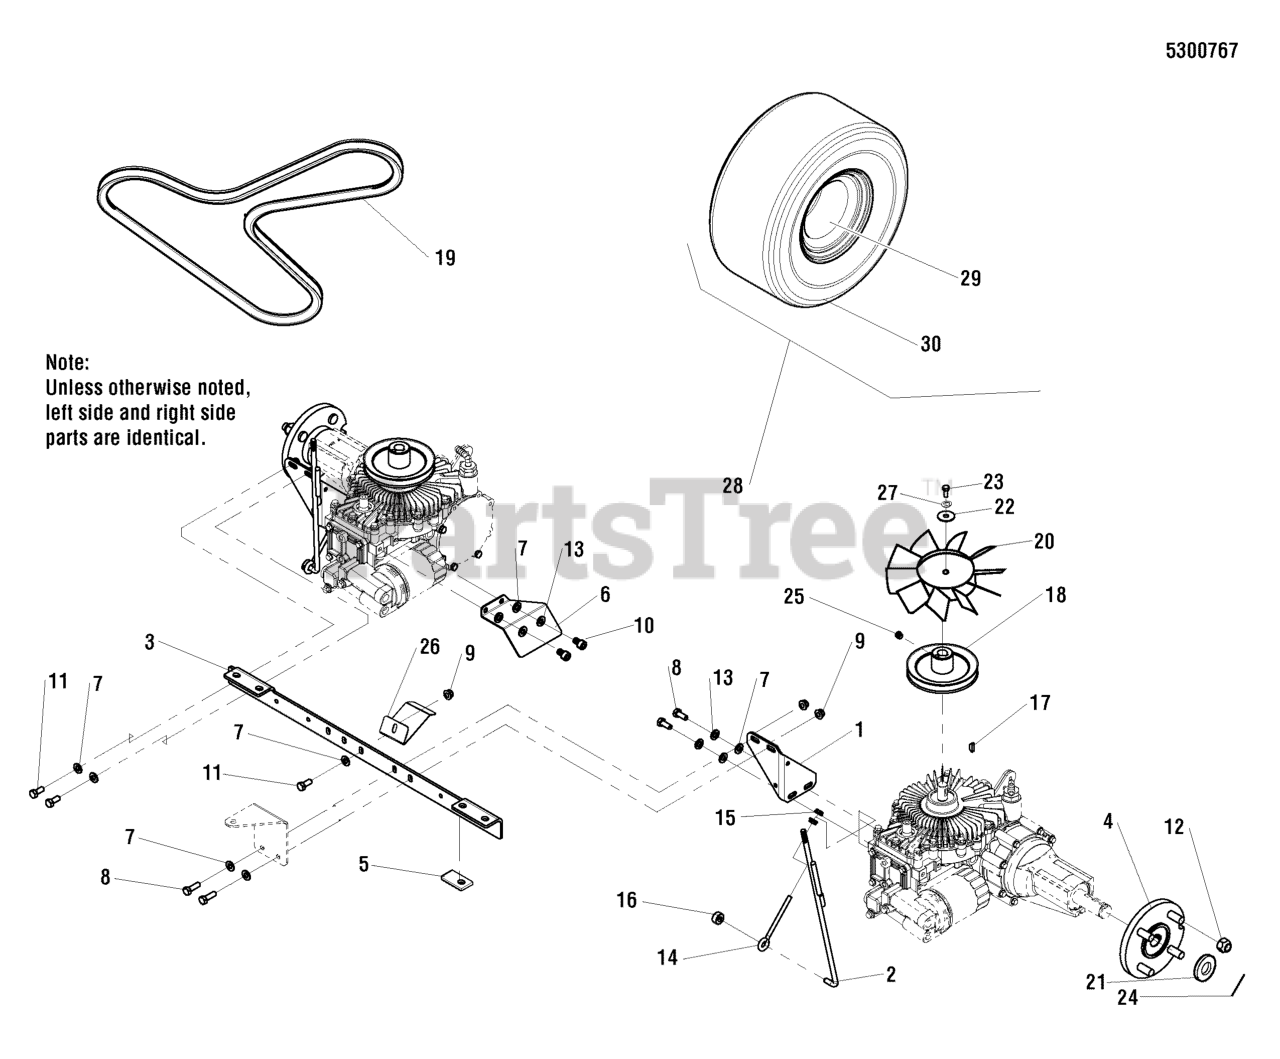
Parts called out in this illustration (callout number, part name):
1	MOUNT, TRANMISSION
3	BRACE, TRANSMISSION
4	HUB, 4-Bolt Tapered
6	GUARD, OIL FILTER
7	WASHER, 5/16" SAE
8	BOLT, 5/16-18 X 1" GRD5 YZ
9	NUT, 5/16-18 HEX NYLOCK FLANGE NUT
10	BOLT, 5/16-18 X 3/4 12PT FLANGE - PATCH
11	BOLT, 5/16-18 X 3/4 GD5
12	NUT, 1/2-20, FOR WHEEL BOLT SILVER
13	WASHER, 5/16 LOCK CZ
14	EYEBOLT, 1/4-20 x 4
15	NUT, 1/4-20 HEX SERR. FLANGE
16	COLLAR, 5/16" Set
17	KEY, Hi-Pro Woodruff
18	PULLEY, TRANSMISSION
19	BELT, SPA-SEC, 66.26" EL, ARAMID, WRAPED
20	FAN, WHITE
21	WASHER, 3/4 SAE
22	WASHER, .265 X 1.50 X .109, YZ
23	BOLT, 1/4 X 20 X 1-3/4 GD5 YZ
24	PIN, COTTER, 1/8 X 1-1/4
25	SET SCREW, 5/16" x 1/4" w/Patch
26	GUARD, HYDRO HOSES - RED
27	WASHER, 1/4 LOCK
28	TIRE, 18 X 8.5 X 8, 4 PLY
29	WHEEL ASSEMBLY, 8 x 7
30	TIRE ONLY (SV)
